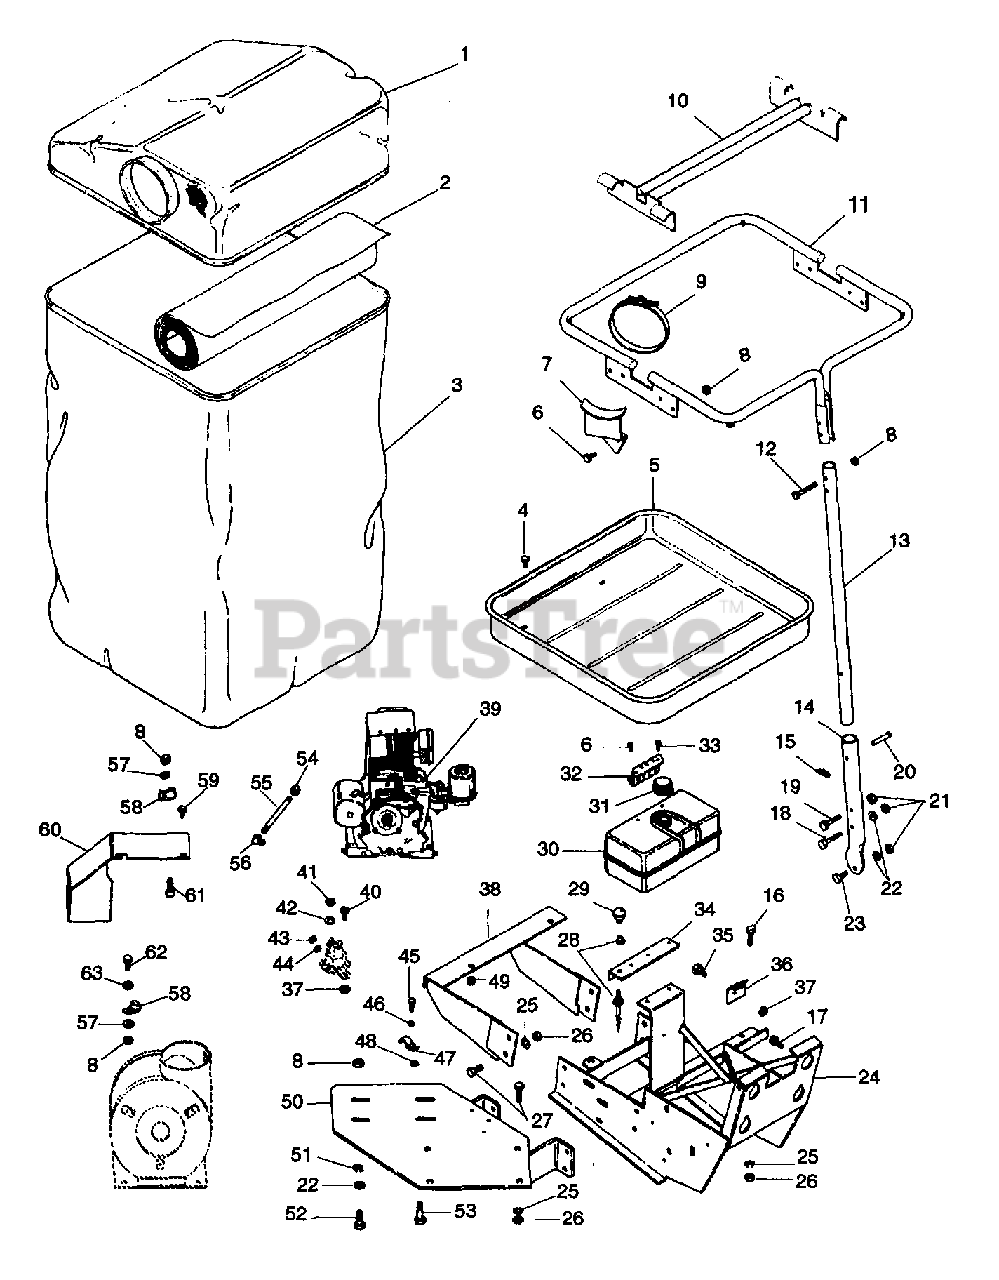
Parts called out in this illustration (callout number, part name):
2	BAGS PLASTIC
4	BLT-RDHDSQNK .31-18X.75 GR5 PL
5	BAG TRAY
6	BLT-HEX .31-18X.75 PL GR2
7	BRACKET-ELBOW SUPPORT
8	NUT-LK .312-18 GR A PL
9	CLAMP-HOSE WRM 2.13/8.62X.56
10	CENTER BAG SUPPORT
11	SUPPORT, BAG
12	BLT-HEX .31-18X2.25 PL GR2
13	TUBE SUPPORT
14	TUBE MOUNTING
15	PIN-HAIR INT .08X.18X1.18
16	BLT-HEX .50-13X1.50 PL GR5
17	SCREW - FLG WIZ LOCK HH PL
18	BLT-HEX .38-16X2.25 PL GR2
19	BLT-HEX .38-16X2.00 PL GR2
20	CLEVIS PIN
21	NUT-LK-CTR .375-16 GR A PL
22	WSHR-FL-STL .38X.875X.083 PL
23	BLT-HEX .38-16X1.00 PL GR5
25	WSHR-LK .500X.151 HVY PL
26	NUT .50-13 PL
27	BLT-HEX .50-13X1.25 PL GR2
28	CHOKE CONTROL
29	PUSH/PULL CONTROL KNOB
30	FUEL TANK
31	FUEL CAP
32	TANK BRACKET
33	SCREW TECUMSEH 42584-60
34	CABLE PLATE
35	BLT-HEX .25-20X.50 PL GR2
37	NUT-LK-CTR .250-20 PL
38	BAG SUPPORT WELDMENT
39	TEC HS40 W/ES
40	BLT-HEX .25-20X.75 PL GR2
41	NUT-JAM .312-24 PL
42	WSHR-LK-INT .313X.030 PL
43	NUT 10-32 PL
44	WSHR-LK 10X.047 MED PL
45	BLT-HEX 10-24X.75 PL GR2
46	WSHR-FL-STL.281X.62X.065 PL
47	J-CLAMP
48	NUT-LK TOP 10-24 PL
49	NUT-FLG. .312-18 PL
50	ENGINE PLATE
51	WSHR-LK-EXT .313X.030 PL
52	BLT-HEX .31-18X1.50 PL GR5
53	BLT-HEX .31-18X1.75 GR5
54	HEX CAP
55	OIL DRAIN PIPE
56	STREET ELBOW
57	WSHR-FL-STL .250X.500X.049
59	SCR-TAP .312-18X.50 HWH PL TR
60	BELT COVER
61	BLT-HEX .31-18X.50 PL GR2
62	BLT-HEX .31-18X1.00 PL GR 2
63	NUT-HEAVY .312-18 PL
